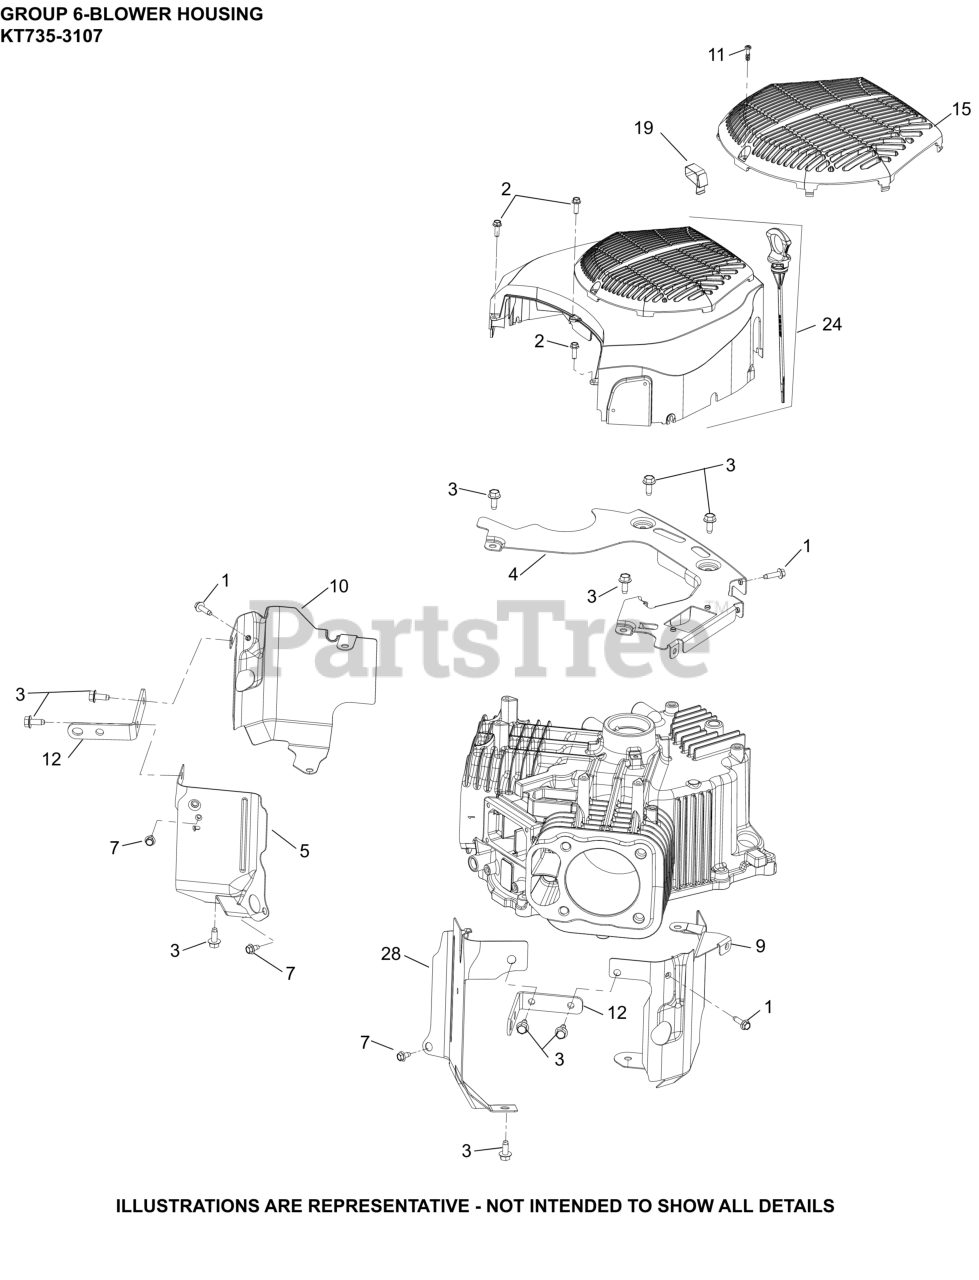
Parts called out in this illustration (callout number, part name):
1	SCREW, THD FRM-USE 25 086 473-S
2	SCREW, HI-LOW
3	SCREW, THREAD FORMING
4	PLATE, BACKING
5	BAFFLE, VALLEY #1
7	SCREW, THREAD FORMING
9	BAFFLE, LEFT BARREL
10	BAFFLE, RIGHT BARREL
11	SCREW, M5-2.42 (PT) THREAD
12	STRAP, LIFTING
15	GUARD, FIXED
19	CLIP, BLOWER HOUSING
24	KIT, BLOWER HOUSING
28	BAFFLE, VALLEY #2
